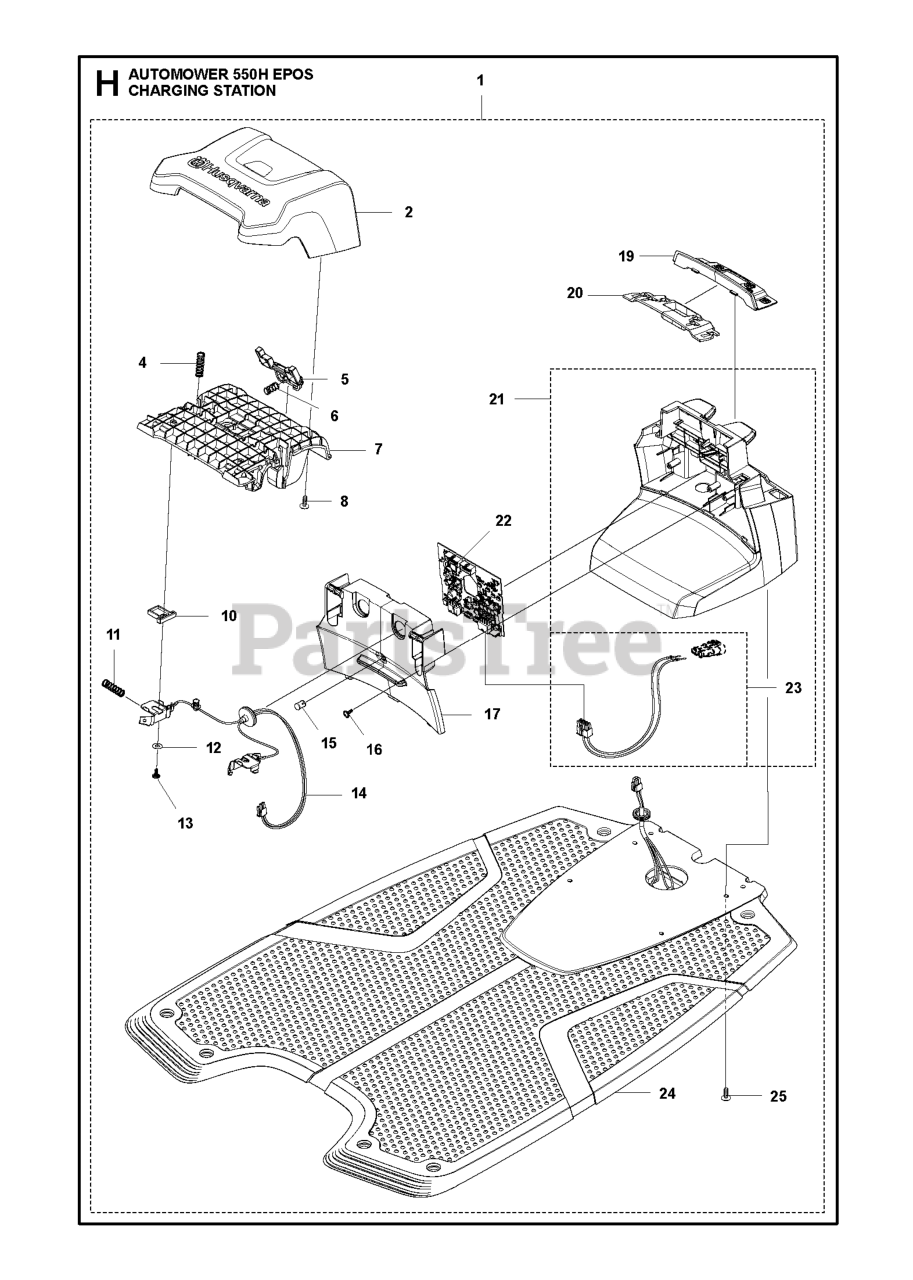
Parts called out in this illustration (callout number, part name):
1	CHARGING STATION 550Z HI-CUT N
2	CAP CHARGING STATION
4	SPRING SPRING CAP
5	BUTTON CHARGING STATION, RELEA
6	SPRING STOP BUTTON
7	FRAME CHARGING STATION
8	SCREW 14MM
11	SPRING SPRING CAP
12	WASHER
13	SCREW 14MM
14	CABLE ASSY CHARGING CONTACTS
15	LENS DIODE
16	SCREW 14MM
17	LID CHARGING STATION 320, ONE
19	PANEL CHARGING STATION NO TERM
20	HOLDER CHARGING STATION
21	HOUSING KIT 550H EPOS
22	PRINTED CIRCUIT ASSY P2 CHARGI
23	CABLE KIT GENERATOR BOARD SPAR
24	BASE ASSY CHARGING STATION
25	SCREW 14MM
